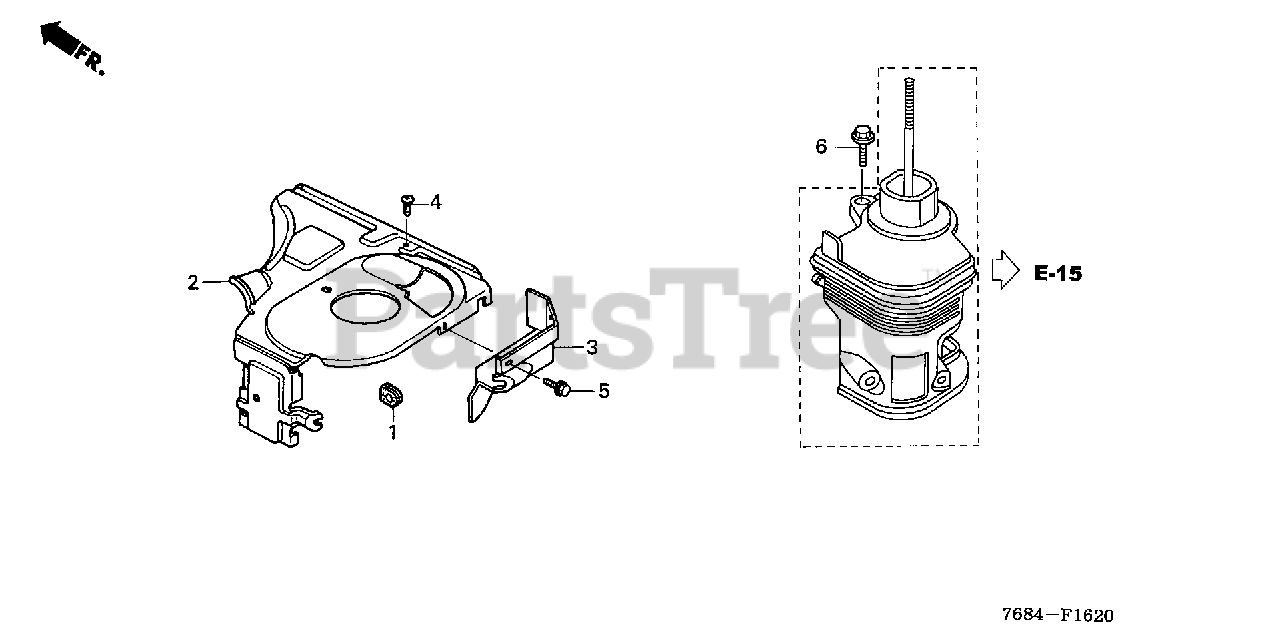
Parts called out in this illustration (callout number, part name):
1	GROMMET, OIL PIPE HOLDER
2	COVER, CONTROL
3	COVER, AIR IN.
4	SCREW, PAN (6X8)
5	BOLT, FLANGE (6X8)
6	BOLT, FLANGE (6X35)
